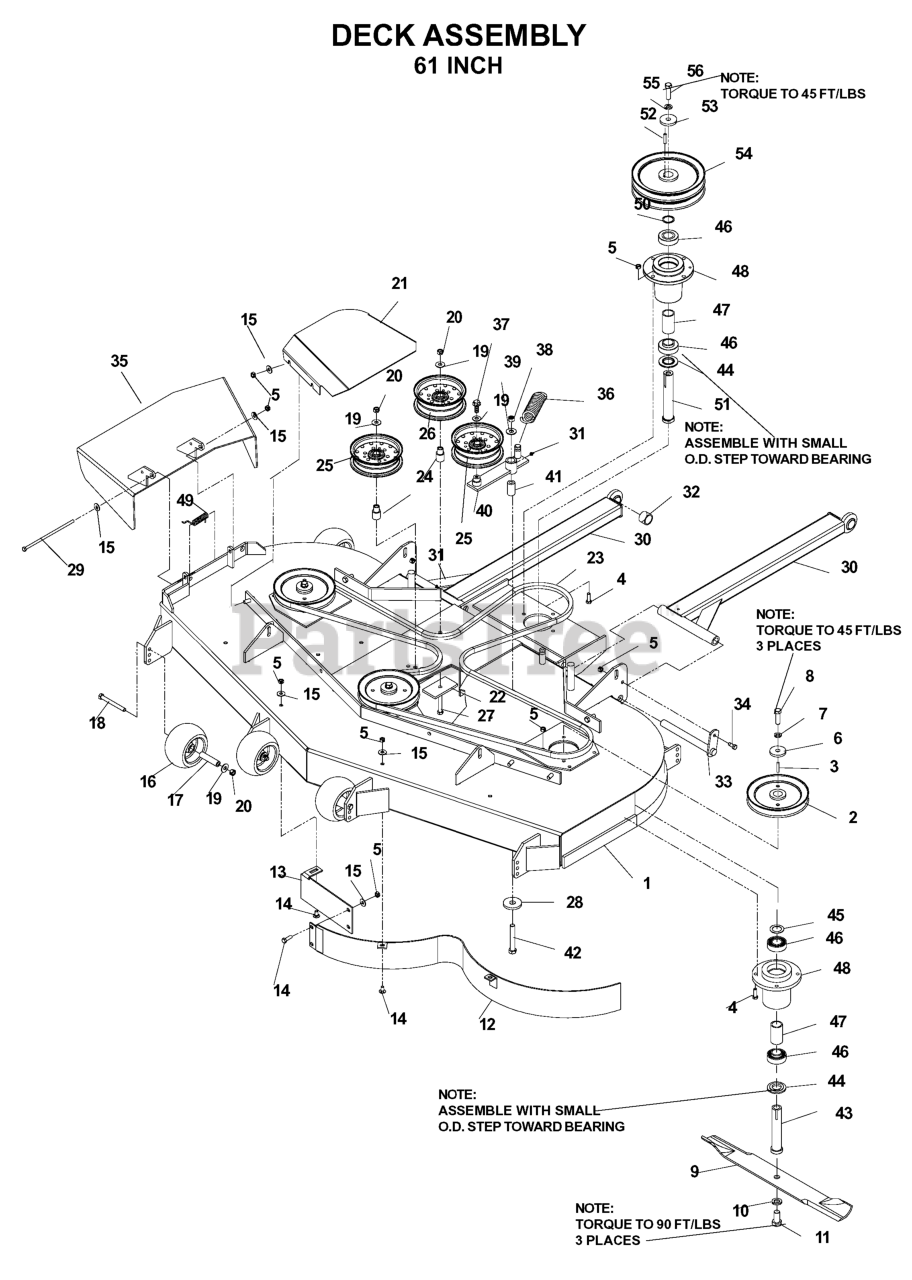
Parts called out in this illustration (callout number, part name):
1	DECK W/DECALS 61" HUS WSL
3	KEY 1/4 SQ X 1 1/8
4	HCS 5/16C X 1
5	NUT 5/16C CENTERLOCK
6	SPINDLE WASHER
7	WASHER 7/16 LOCK
8	HCS 7/16F X 1 1/2
9	BLADE OEM 21" (61" DECK)
10	LOCKWASHER 5/8
11	HCS 5/8F X 1 1/4
12	MAIN BAFFLE - 61" BLK
13	CENTER BAFFLE - 61
14	CARRIAGE BOLT 5/16C X 5/8"
15	WASHER 5/16 FLAT
16	ANTI-SCALP ROLLER
18	HCS 3/8C X 3 1/2
19	WASHER 3/8 FLAT
20	NUT 3/8C CENTERBLOCK
21	SHIELD, BELT 61-ORANGE
22	SUPPORT PLATE
23	BELT, DECK
24	IDLER BUSHING
25	IDLER PULLEY
26	IDLER PULLEY (TALL)
27	HCS 3/8C X 2 1/2
28	WASHER, SUPPORT
29	HCS 5/16-18 X 8-1/2 GR 5 ZD
30	STRUT WELDMT, L.H.
31	ZERK
32	SPACER, STRUT
33	PIN WELDMENT
34	HCS 5/16C X 3/4
35	CHUTE 61 ORANGE
36	DECK SPRING
37	4CS 3/8C X 1 SERRATED HEAD
38	NUT 1/2-13 HEX NYLOC ZD
39	WASHER 1/2 FLAT
41	PIVOT BUSHING
42	HCS 1/2C X 3 1/4
43	SPINDLE SHAFT
44	COMBO SPACER
45	BUSHING.MACHINE.18.GAUGE
46	BEARING
48	HOUSING, DIE CAST
49	SPRING, TORTION
50	BUSHING.MACHINE.18.GAUGE
51	SPINDLE SHAFT
52	KEY 1/4 SQ X 1 1/8
53	SPINDLE WASHER
54	SHEAVE WSL
55	WASHER 7/16 LOCK
56	HCS 7/16F X 1 1/2
539105661	SHIELD, BELT 61-ORANGE
